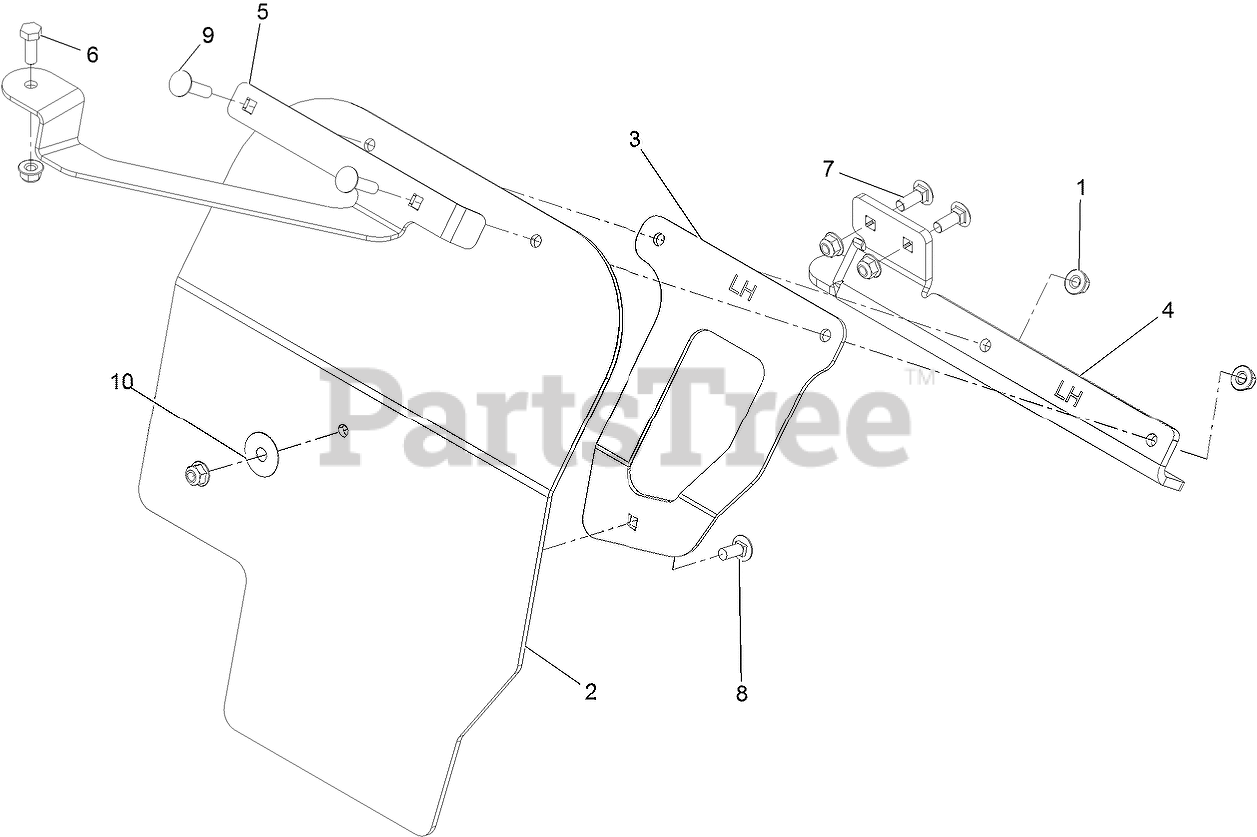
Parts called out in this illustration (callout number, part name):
1	NUT-HF, NI
2	LH MUD FLAP
3	SUPPORT, LH MUD FLAP
4	BRACKET, LH MUD FLAP
5	FORWARD SUPPORT, LH MUD FLAP
6	SCREW-HH
7	SCREW-CARR
8	SCREW-CARR
9	Bolt-Carriage 5/16-18 X 1 1/4
10	WASHER-PLAIN
